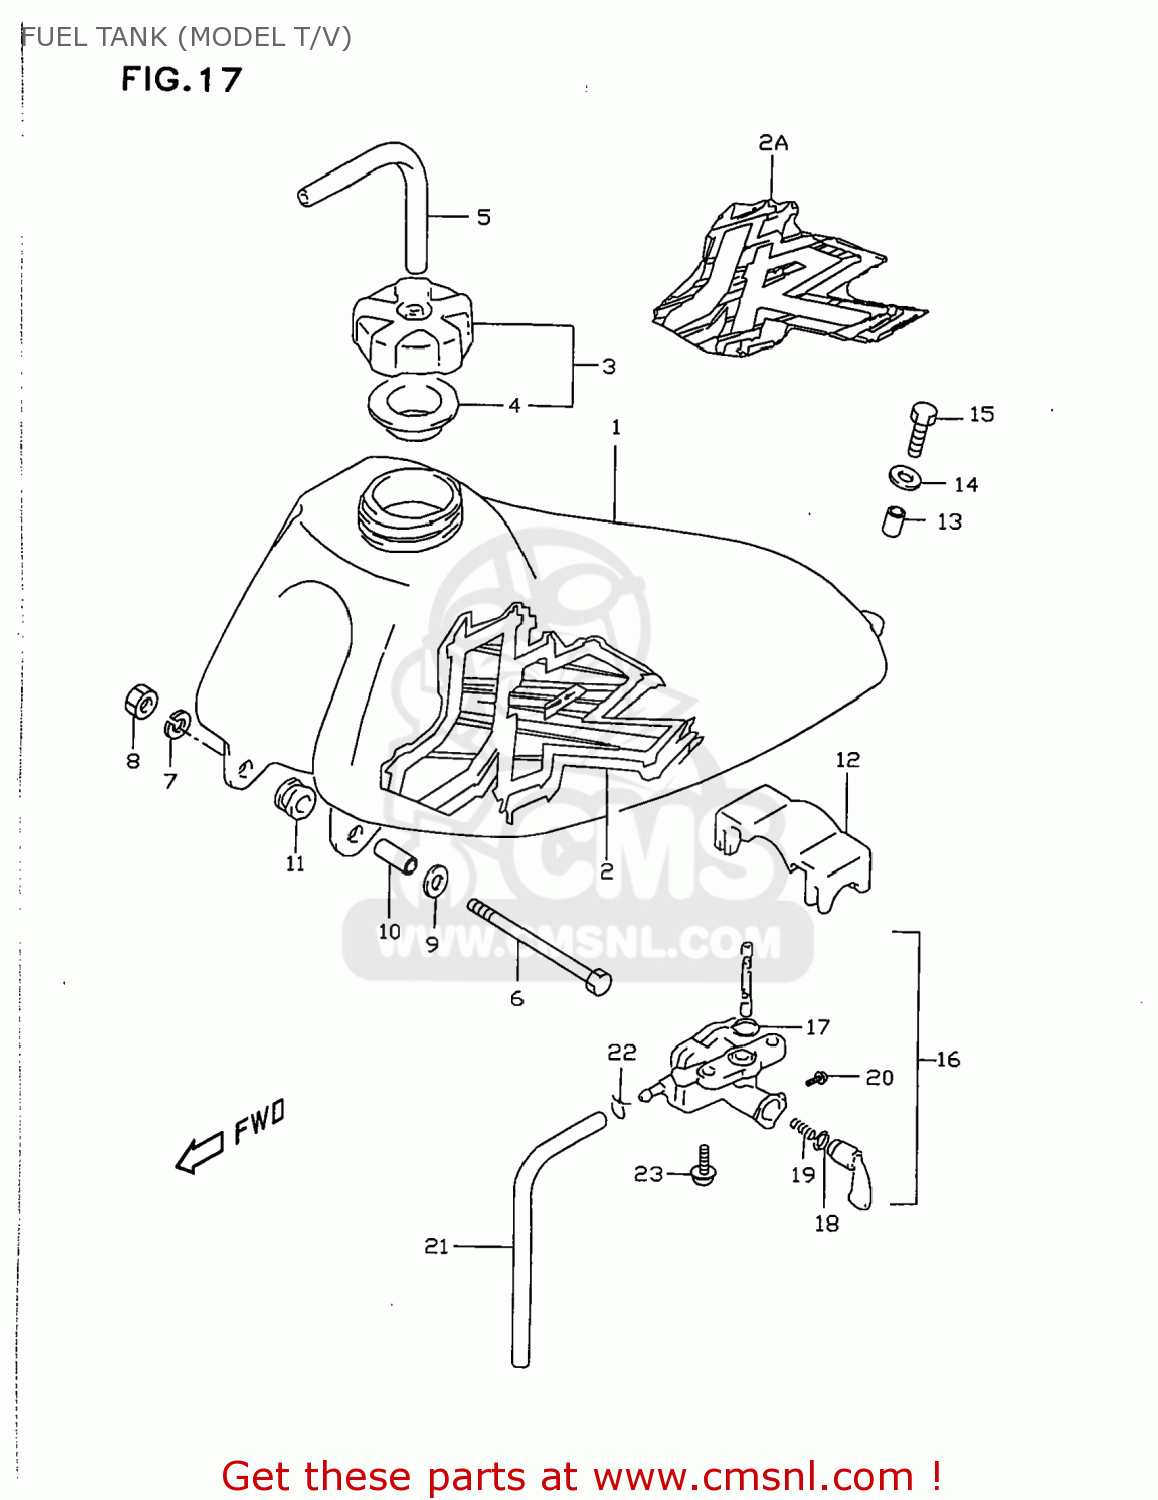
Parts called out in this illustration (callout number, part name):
1	TANK,FUEL
2	EMBLEM SET,FUEL TANK
2A	EMBLEM SET,FRAME TANK
3	CAP,FUEL TANK FILLER
4	GASKET (NAS)
5	HOSE(5X8.2X600)
6	BOLT, FRONT
7	LOCK WASHER
8	NUT 6MM
9	WASHER(6.5X18X1)
10	SPACER (6.8X10X11.5)
11	CUSHION
12	CUSHION,FUEL TANK UPR
13	SPACER(6.5X9X7.2)
14	WASHER(6.5X18X1)
15	BOLT
16	COCK ASSY,FUEL
17	O RING
18	O RING,LEVER
19	SPRING,FUEL COCK VALUE
20	SCREW
21	HOSE(5X8.2X600)
22	CLIP
23	SCREW
